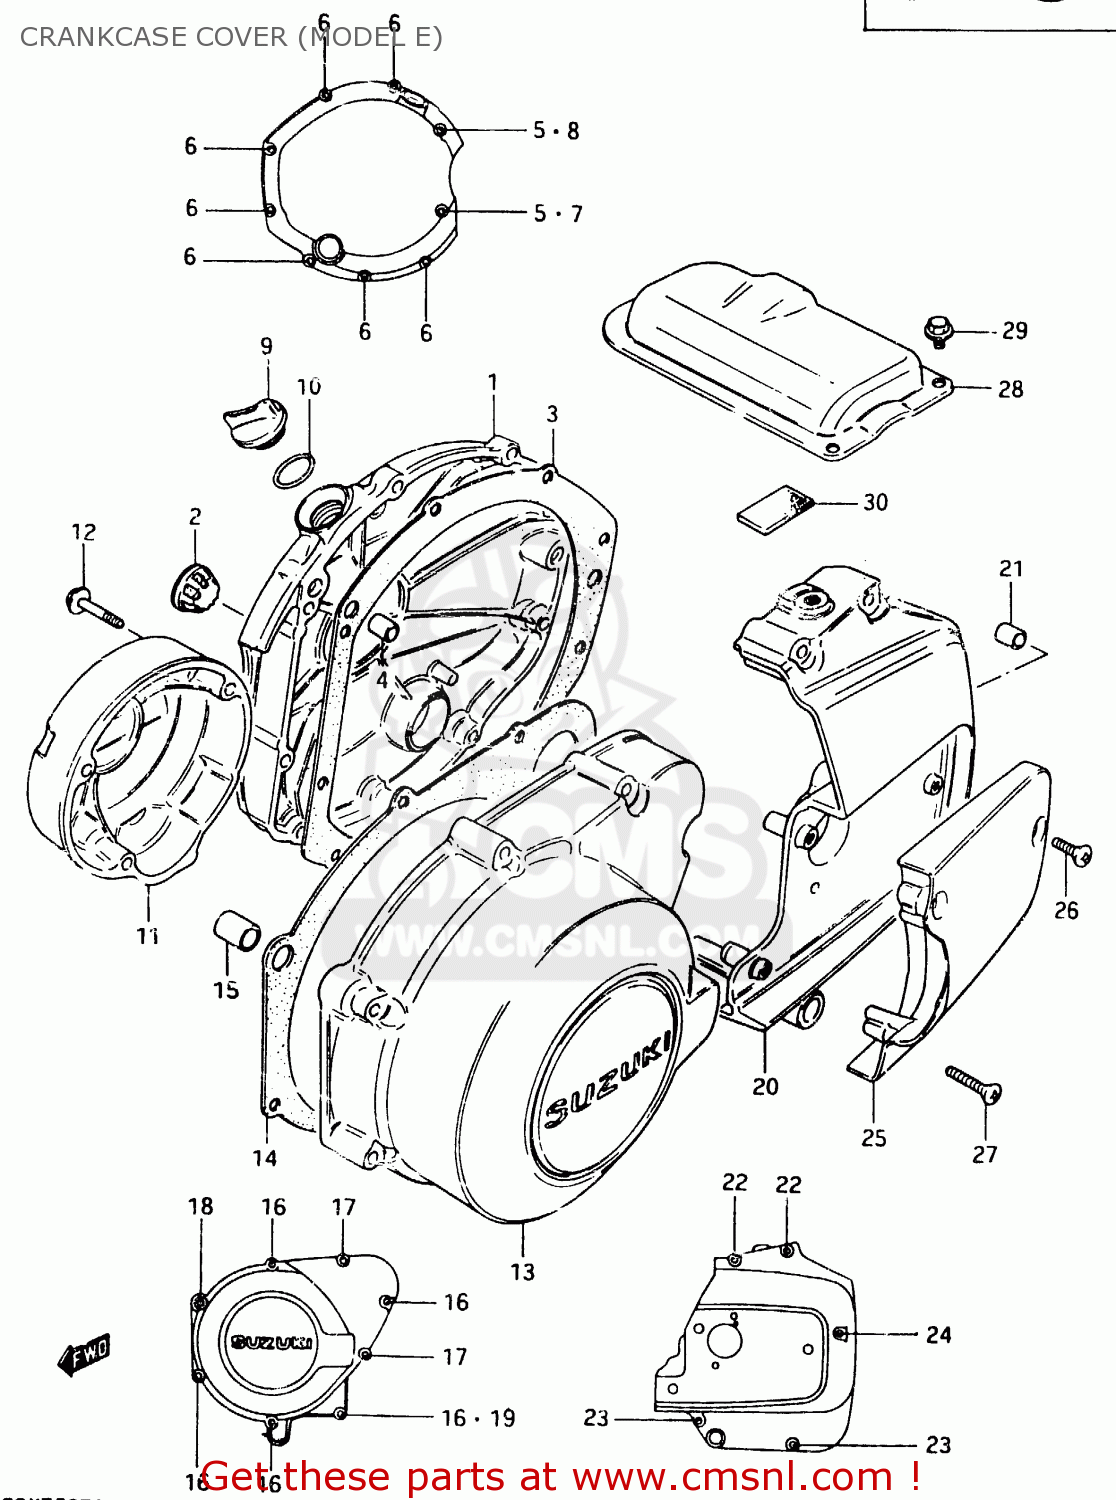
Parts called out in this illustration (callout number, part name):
1	COVER, CLUTCH
2	LENS,OIL LEVEL CHECK
3	GASKET,CLUTCH COVER (MCA)
4	PIN
5	WASHER
6	BOLT 6X25
7	BOLT 6X30
8	BOLT 6X35
9	PLUG
10	O RING(D:3.1,ID:16.8)
11	COVER,CONTACT BREAKER
12	BOLT 5X30
13	COVER,GENERATOR
14	GASKET,MAGNETO COVER (MCA)
15	PIN (11X20)(SUS)
16	BOLT 6X35
17	BOLT 6X40
18	BOLT
19	WASHER
20	COVER, ENGINE SPROCKET
21	PIN
22	BOLT 6X40
23	BOLT 6X50
24	BOLT (6X70)
25	CAP,CLUTCH REL
26	SCREW
27	SCREW 5X30
28	COVER,STARTER MOTOR
29	BOLT
30	DAMPER,STARTER MOTOR CLUTCH
